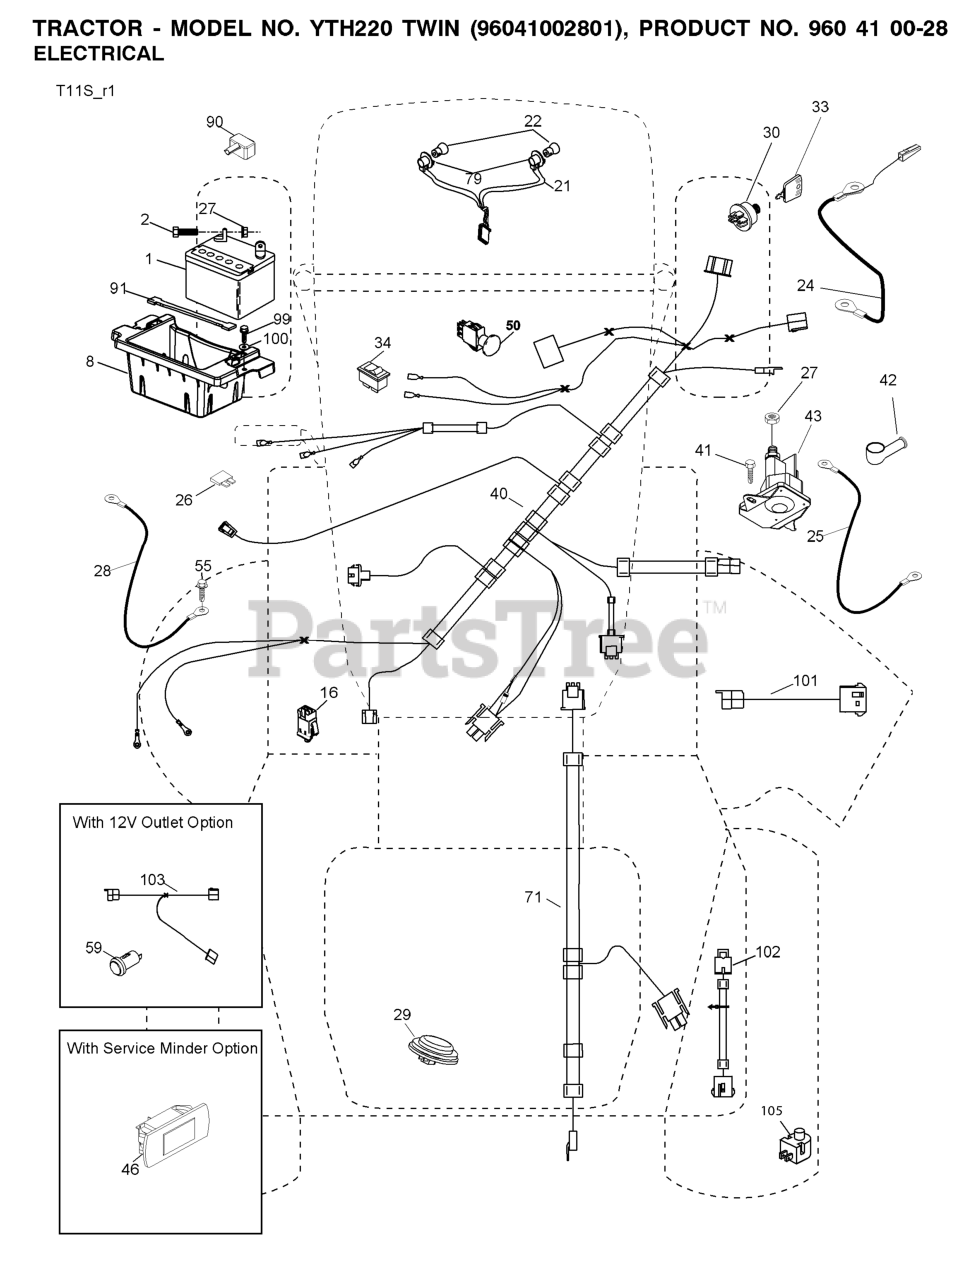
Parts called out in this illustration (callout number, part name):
1	Battery 12 Volt 25 Amp
2	BOLT.HEX.1/4.X.3/4.DICHROMATE
8	BOX.BATTERY.MOUNT.FRONT.LT
16	SWITCH INTERLOOK PUSH-IN
21	HARNESS ASSY LIGHT
24	CABLE.BATT.POS.WIRE.TG.DA SOL
25	CABLE.STARTER.6G.BL/RED.17.5
26	FUSE 20AMP
27	NUT
28	CABLE GROUND 6 GA 21" 90T BLK
29	SWITCH.SEAT.DELTA.OPC.
30	SWITCH.IGN.DELTA.W.LGH.ROS
33	KEY.CHAIN.BLISTER.PACK.GEN.INT
40	HARNESS.IGN.DASH.HUQ/P
41	SCREW
42	TERMINAL COVER
43	SOLENOID.W/BRASS.PLUNGER
50	RP.PTO.SWITCH.8 TERMINAL.BLACK
55	SCREW 5/16"
71	HARNESS-CHASSIS SUB
79	BULB HOLDER ASM.
90	COVER.TERMINAL.BATTERY
91	STRAP.BATTERY.MOUNT.FRONT(2 2)
99	SCREW HEXWSHR 1/4-20X3/4
101	PIGTAIL.MATNLK.NEW.HAR
102	HARNESS PIGTAIL PCH TEX ROS
105	REVERSE SWITCH
